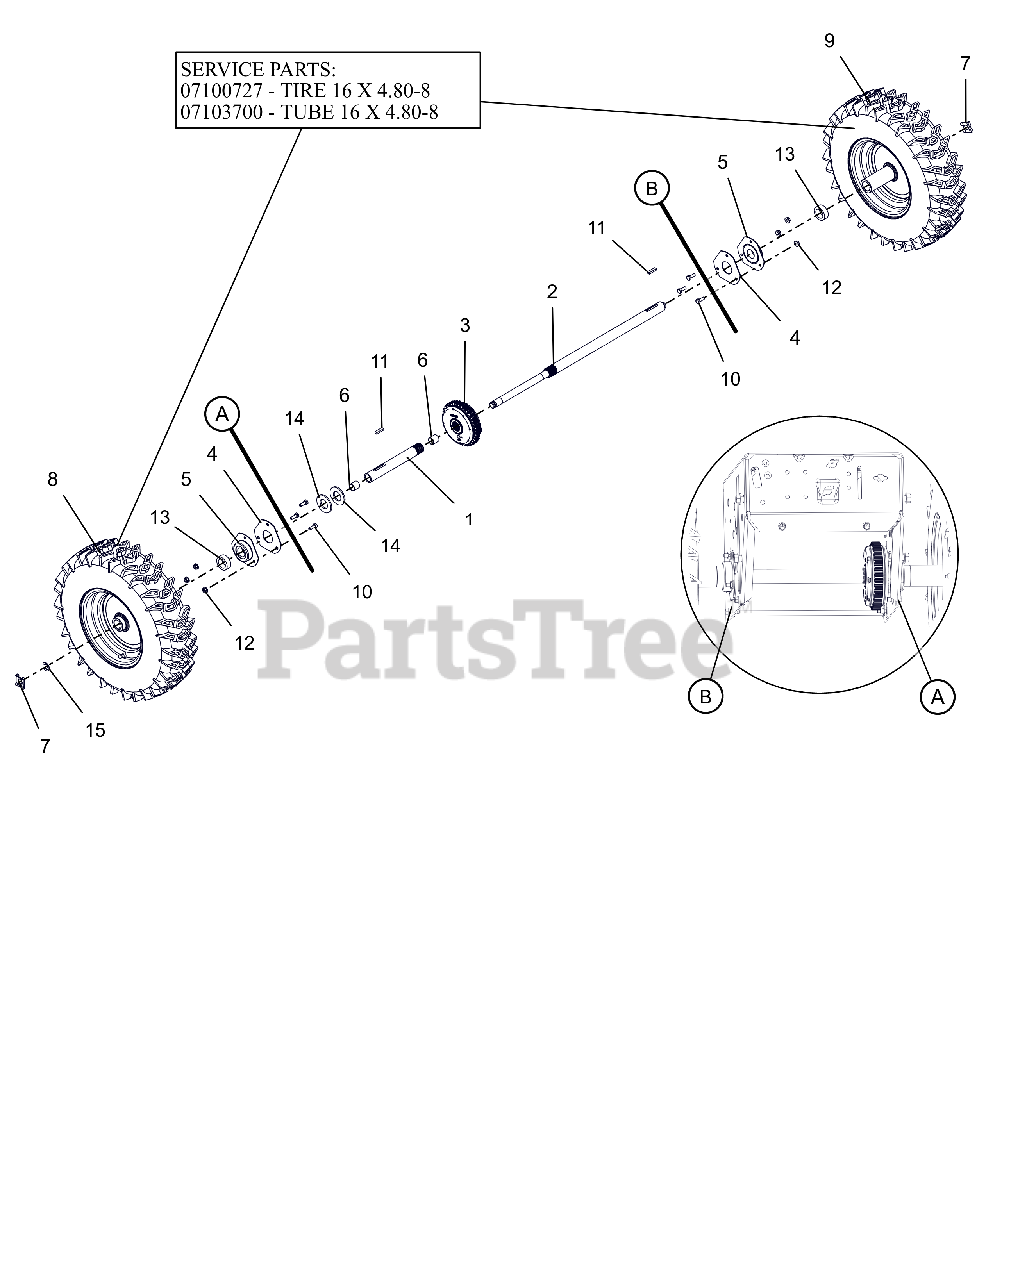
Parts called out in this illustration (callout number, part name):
1	AXLE, SHORT-AUTO W/BUSHINGS
2	AXLE, LONG-PRO AUTO DIFF
3	DIFFERENTIAL, AUTOMATIC
4	PLATE, BEARING SPACER
5	BRG-FLG 1.003/1.000 3 BOLT
6	BSHG-SLV .706X.764X.75 BRZ
7	CLIP, SNAP .625 DIA
8	TIRE/WHEEL,RH 16X4.8-8 DIFF T2
8-9	TIRE, 4.80-8 K478
8-9	TUBE
9	TIRE/WHEEL,LH 16X4.8-8 DIFF T2
10	BLT, HEX .25-20X.75 G5 ZCC
11	KEY-RECT .25X.188X1.00
12	NUT-LK-CTR-FLG .25-20 ZC120
13	SPACER, PRO AXLE BEARING
14	WSHR, FLT 1.062X2.000X.134 ZCC
15	RG-RTNG-EXT .625X.042
